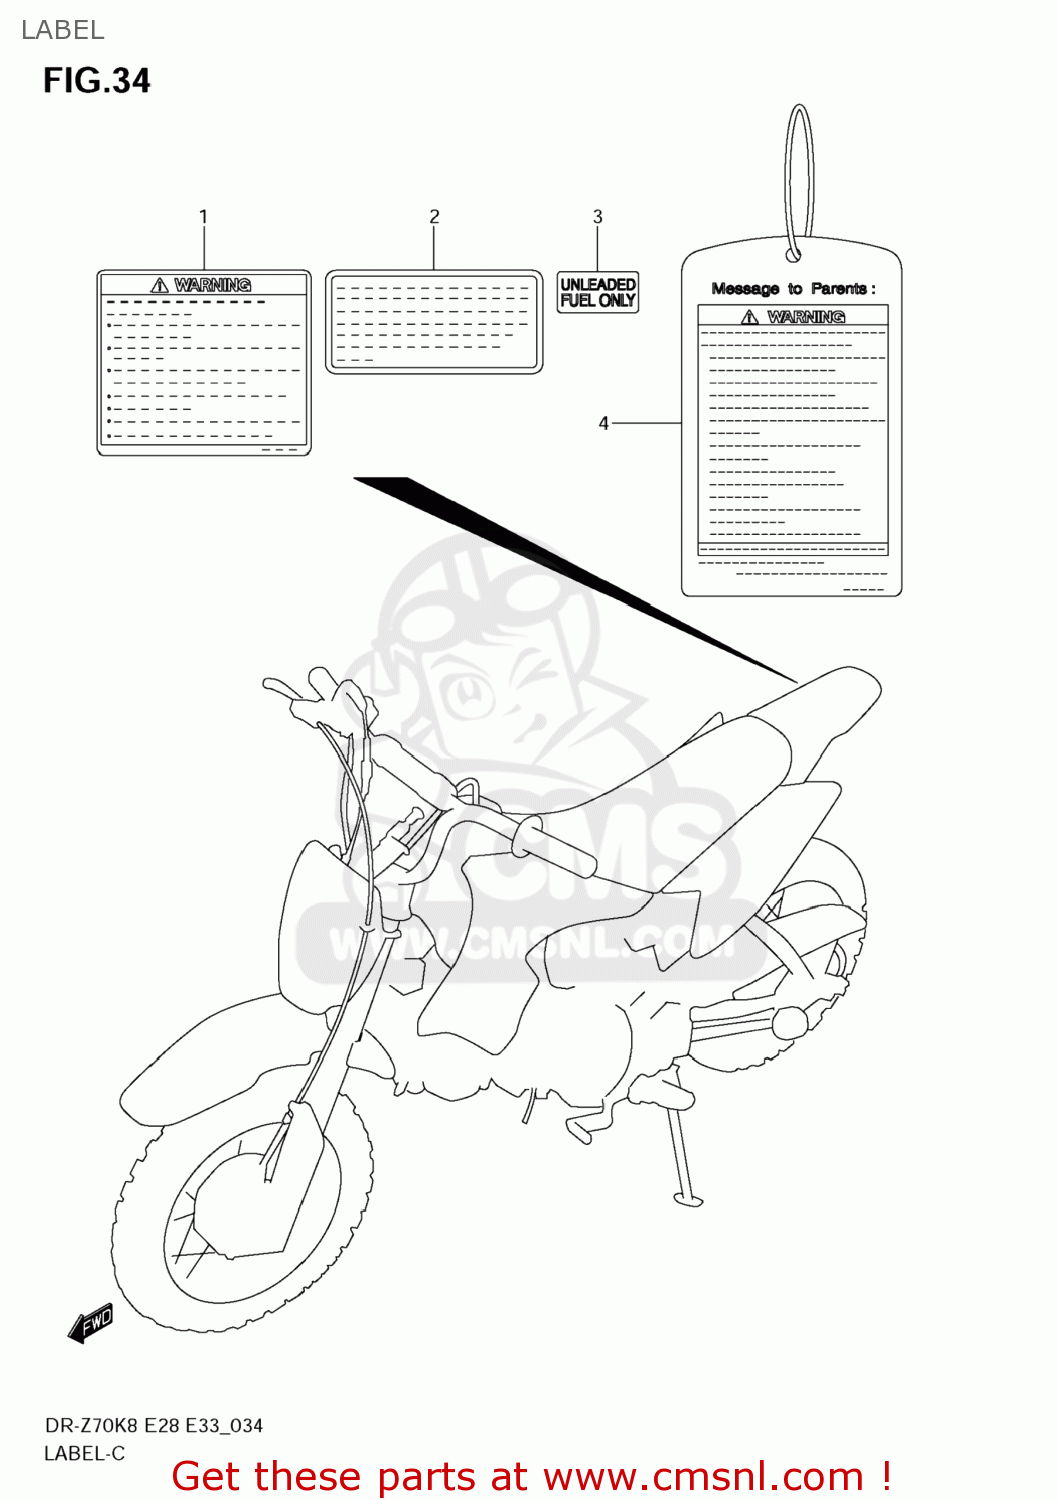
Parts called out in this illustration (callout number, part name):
1	LABEL,GENERAL WARNING
2	LABEL,MANUAL NOTICE
3	LABEL,UNLEADED FUEL
4	TAG
5	MANUAL,OWNER'S
